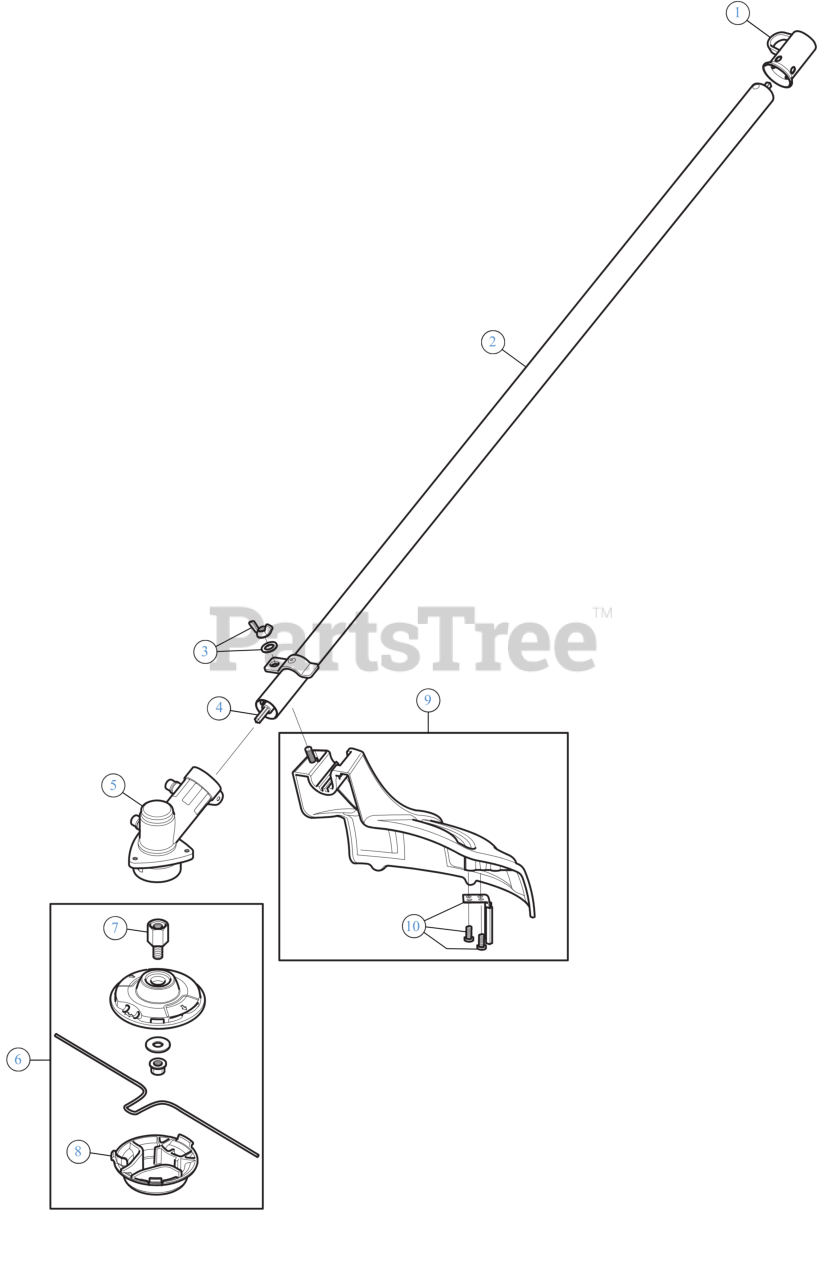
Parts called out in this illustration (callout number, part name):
1	HANGER
2	LOWER DRIVE SHAFT HOUSING
3	BLADE GUARD MOUNTING HARDWARE
4	FLEX SHAFT LOWER
5	GEARBOX
6	CUTTING HEAD ASSEMBLY
7	SPACER GEARBOX
8	HEAD FIXED LINE BT
9	GUARD/BLADE ASM
10	BLADE ASSEMBLY W/HDW
